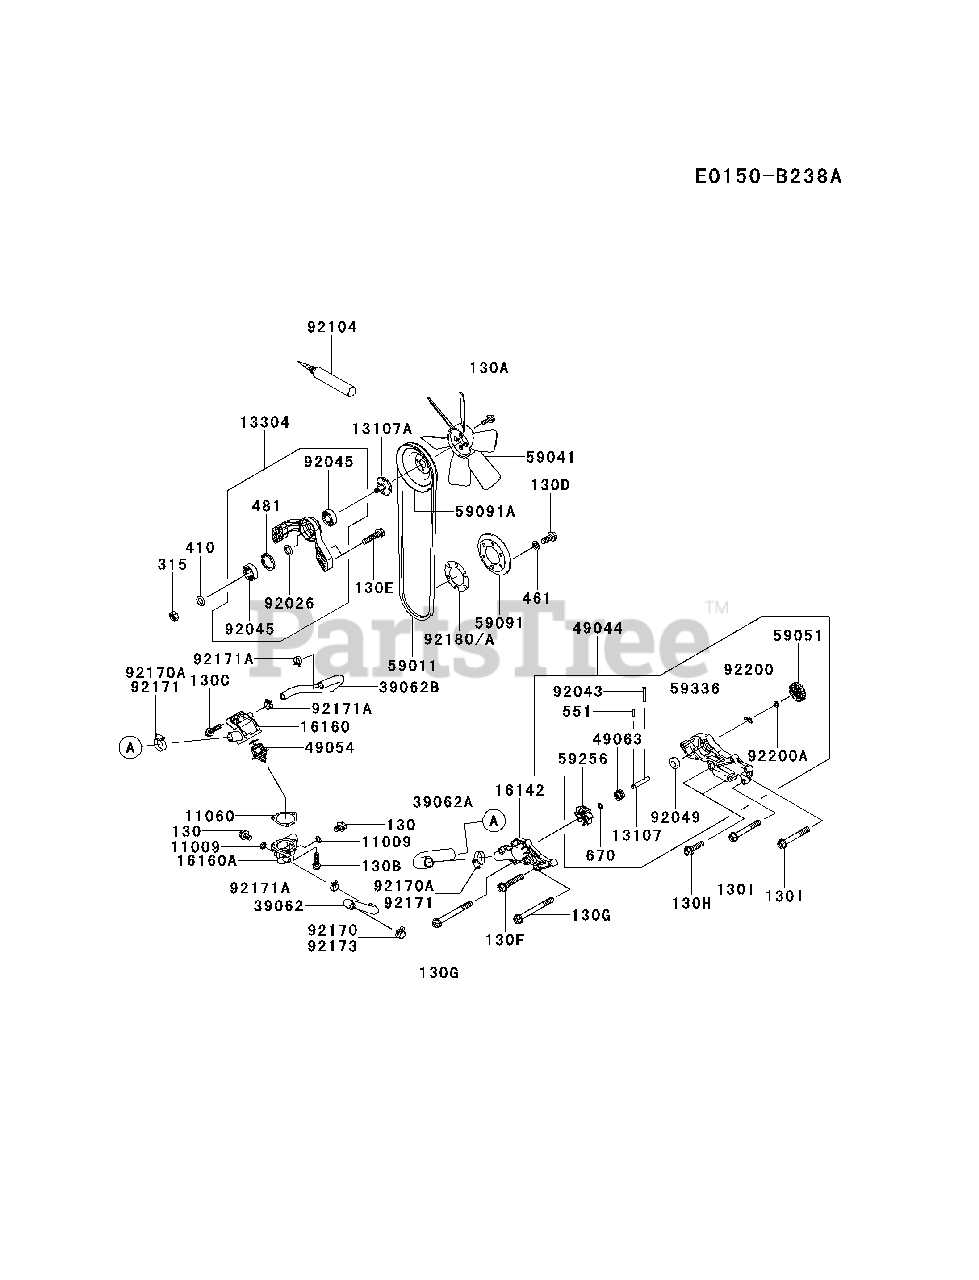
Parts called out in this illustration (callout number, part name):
130E	BOLT-FLANGED,8X35
130F	BOLT-FLANGED,8X45
130G	BOLT-FLANGED,8X80
130H	BOLT-FLANGED,8X30
130I	BOLT-FLANGED,8X60
315	NUT-HEX-FINE,10MM
410	WASHER-PLAIN-SMALL,10MM
461	WASHER-SPRING,8MM
481	CIRCLIP,28MM
551	PIN-DOWEL,3X14
670	O RING,7MM
